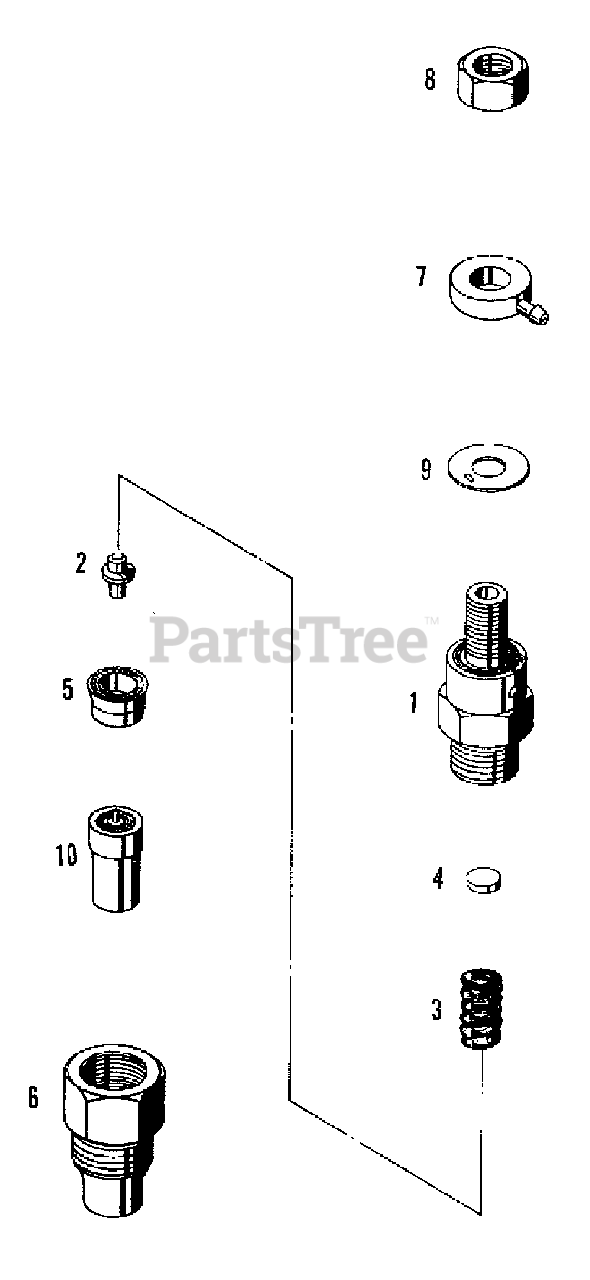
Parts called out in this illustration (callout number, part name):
1	BODY, nozzle holder
2	ROD, push
3	SPRING, nozzle
6	NUT, retaining
